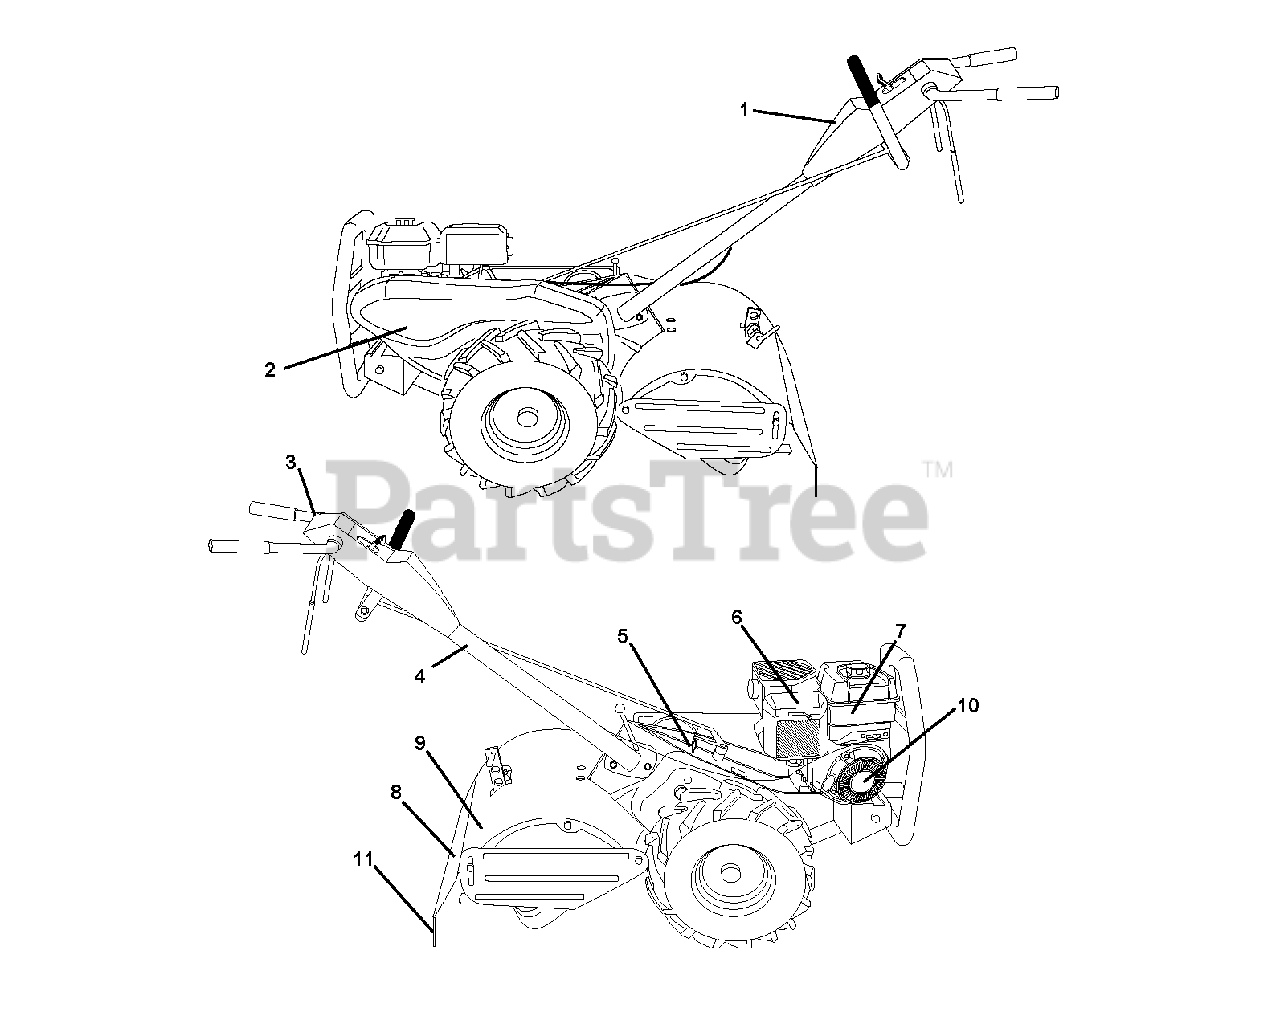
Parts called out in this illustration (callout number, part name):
5	DECAL.SHIFT.INDICATOR.TILLER
9	DECAL EUROPE STANDARD CE
10	DECAL, REWIND STARTER, B&S
